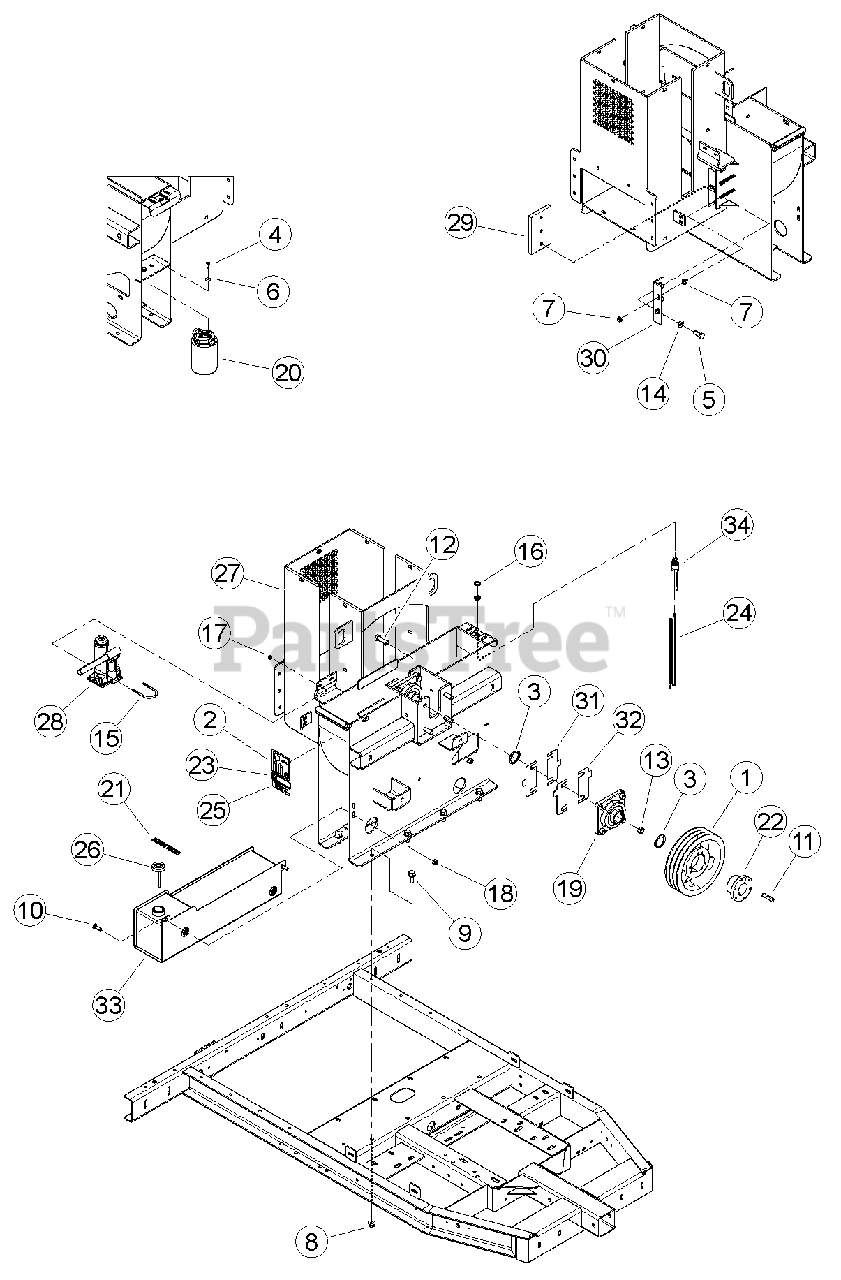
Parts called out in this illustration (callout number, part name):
1	SHEAVE, 3BQ9.4 SK
2	DECAL, 111 DB (CE COMPLIANT ONLY)
3	RING, 1-3/4 EXT HEAVY DUTY SNAP
4	BOLT, 1/4 X 3/4 GR5 HEX HD ZP
5	BOLT, 1/2 X 1-1/4" GR5 HHCS NC ZP
6	WASHER, 1/4" FLAT ZP
7	NUT, 3/8" SERRATED FLANGE NC ZP
8	NUT, 1/2-13 NYLOCK FLANGE
9	BOLT, 1/2 -13 X 1-1/4 FLANGE NC
10	BOLT, 3/8 X 1-1/4" GR5 CRG NC ZP
11	KEY, 3/8" SQ X 2" LG PLAIN
12	BOLT, 9/16 X 1-3/4 HEX GR5 ZP
13	NUT, 9/16 CENTER LOCK GRB ZP
14	WASHER, 1/2 HI-STRENGTH SAE ZP
15	U-BOLT, 1/4 X 1-1/2 PIPE
16	NUT, 5/8-32 JAM
17	NUT, 1/4-20 NYLOCK-FLANGE
18	NUT, 3/8-16 NYLOCK FLANGE
19	BEARING, 1-3/4 4 BOLT FLANGE
20	ASSEMBLY, HYDRAULIC FILTER
21	DECAL, HYDRAULIC FLUID
22	BUSHING, SK 1-3/4"
23	DECAL, 76628S INFORMATION (CE COMPLIANT ONLY)
24	WIRE ASSEMBLY, 37" FM SPADE AND RING
25	DECAL, ATLANTIC BRIDGE LTD INFO (CE COMPLIANT ONLY)
26	CAP, HYDRAULIC W/ DIPSTICK
27	WELDMENT, 6 IN CHIPPER HOUSING
28	JACK, HYDRAULIC 2 TON
29	ANVIL, 6" CHIPPER
30	WELDMENT, BLOCK ADJUSTOR
31	SHIM, 20 GA.
32	SHIM, 16 GA.
33	WELDMENT, HYDRAULIC TANK
34	ASSEMBLY, SEALED SWITCH
